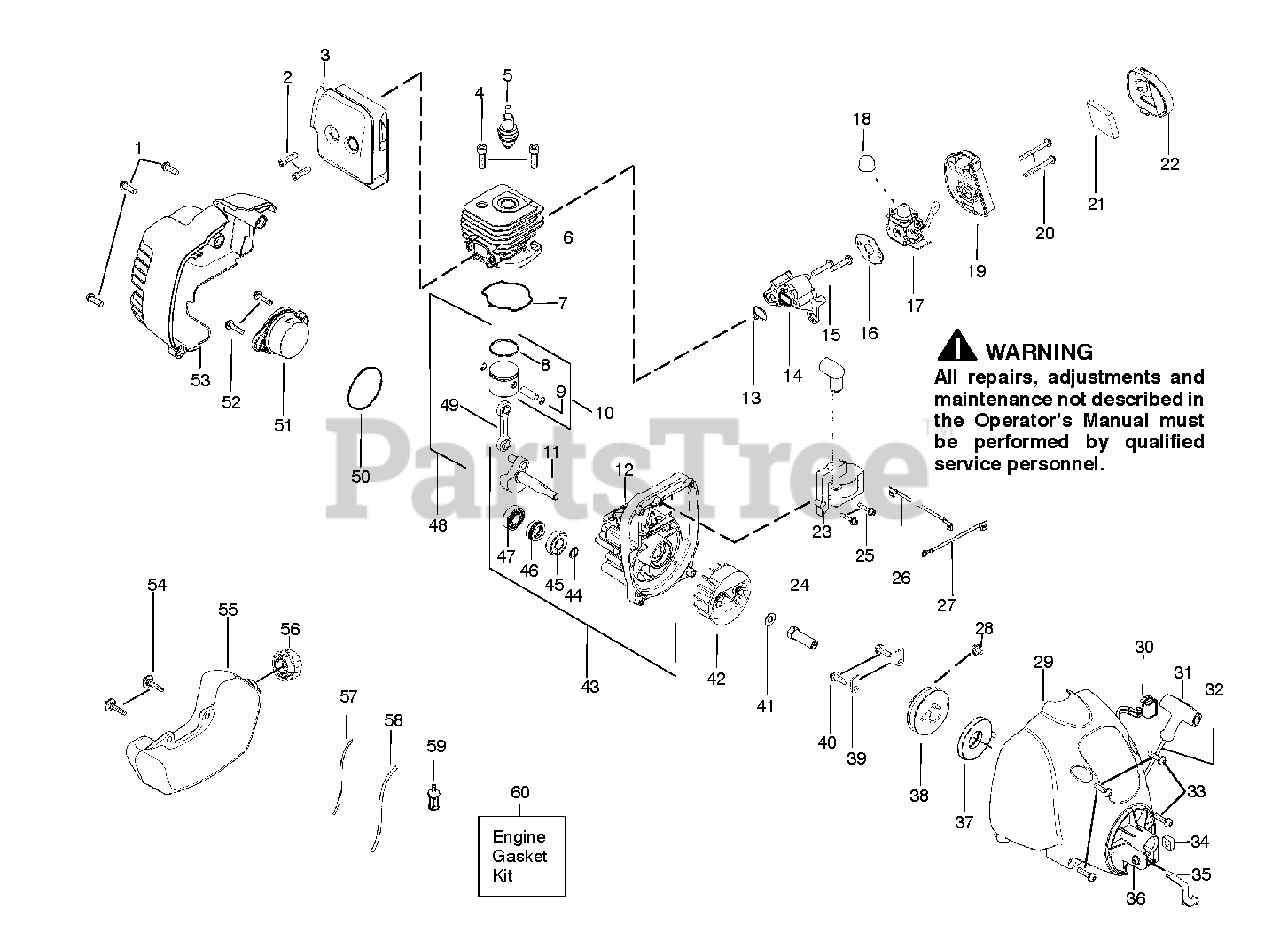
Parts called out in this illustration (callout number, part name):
2	BOLT MUFFLER
3	ASSY MUFFLER SHIELD
5	PLUG-SPARK (RCJ-6Y)
6	CYLINDER MACHINED 25CC LO
7	KIT GASKET 25CC
8	PISTON RING
9	WRIST PIN RET.
10	PISTON
11	ASSY CRANKSHAFT
12	ASSY CRANKCASE
13	KIT GASKET 25CC
14	ADAPTOR CARBURETOR
16	KIT GASKET 25CC
17	Poulan TBD
17	KIT CARB ASSY # C1U-W24
17	KIT CARB ASSY WT670
18	Poulan TBD
18	PURGE BULB ZAMA
18	PURGE BULB 188-16
21	FOAM AIR FILTER
22	COVER AIR BOX
24	DRIVE-COUPLING
26	LEAD WIRE
27	GROUND WIRE
28	SCREW SEMS TOOTHED WASHER
29	FAN HOUSING
30	KIT SWITCH MOMENTARY
31	HANDLE-STARTER
32	KIT ROPE
34	NUT SQUARE
37	STARTER SPRING
38	STARTER PULLEY KIT
39	RETAINER
40	SCREW 8-16 X 9/16 (PLAS
41	WASHER FLAT
42	ASSY FLYWHEEL
43	ASSEMBLY
44	RETAINING RING
45	OUTER BEARING
47	BEARING
48	PISTON KIT
49	KIT-CONN ROD ASSY
50	KIT GASKET 25CC
51	ASSY REAR PLUG
53	CYLINDER COVER
54	SCREW FUEL TANK RETAINER
55	ASSY FUEL TANK (FL)
56	CAP ASSY W/ RETAINER
57	KIT-LINE
58	LINE KIT
59	FUEL PICK-UP ASSY
60	KIT GASKET 25CC
